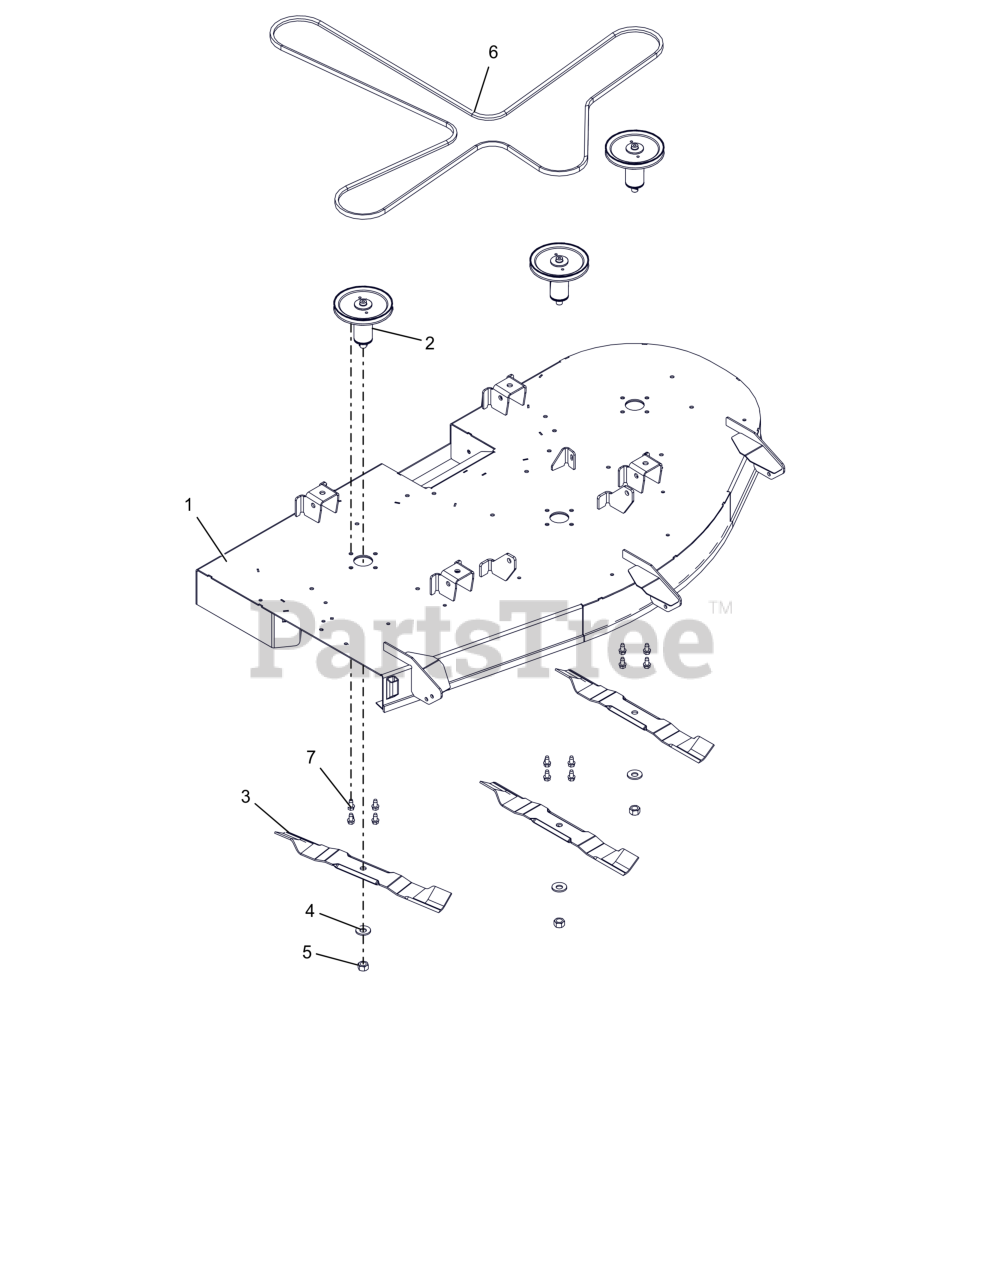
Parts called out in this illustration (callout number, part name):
1	KIT, 60" GRAVELY DECK W/DECALS
2	KIT, DECK SPINDLE ASM-60
3	BLADE, 21" 35 DEG
4	WSHR-BLVL .669X1.535X.138
5	NUT-STD .625-18 ZCC
6	BELT, HA
7	SCR,TAP .375-16X.75 HWH TR ZCC
